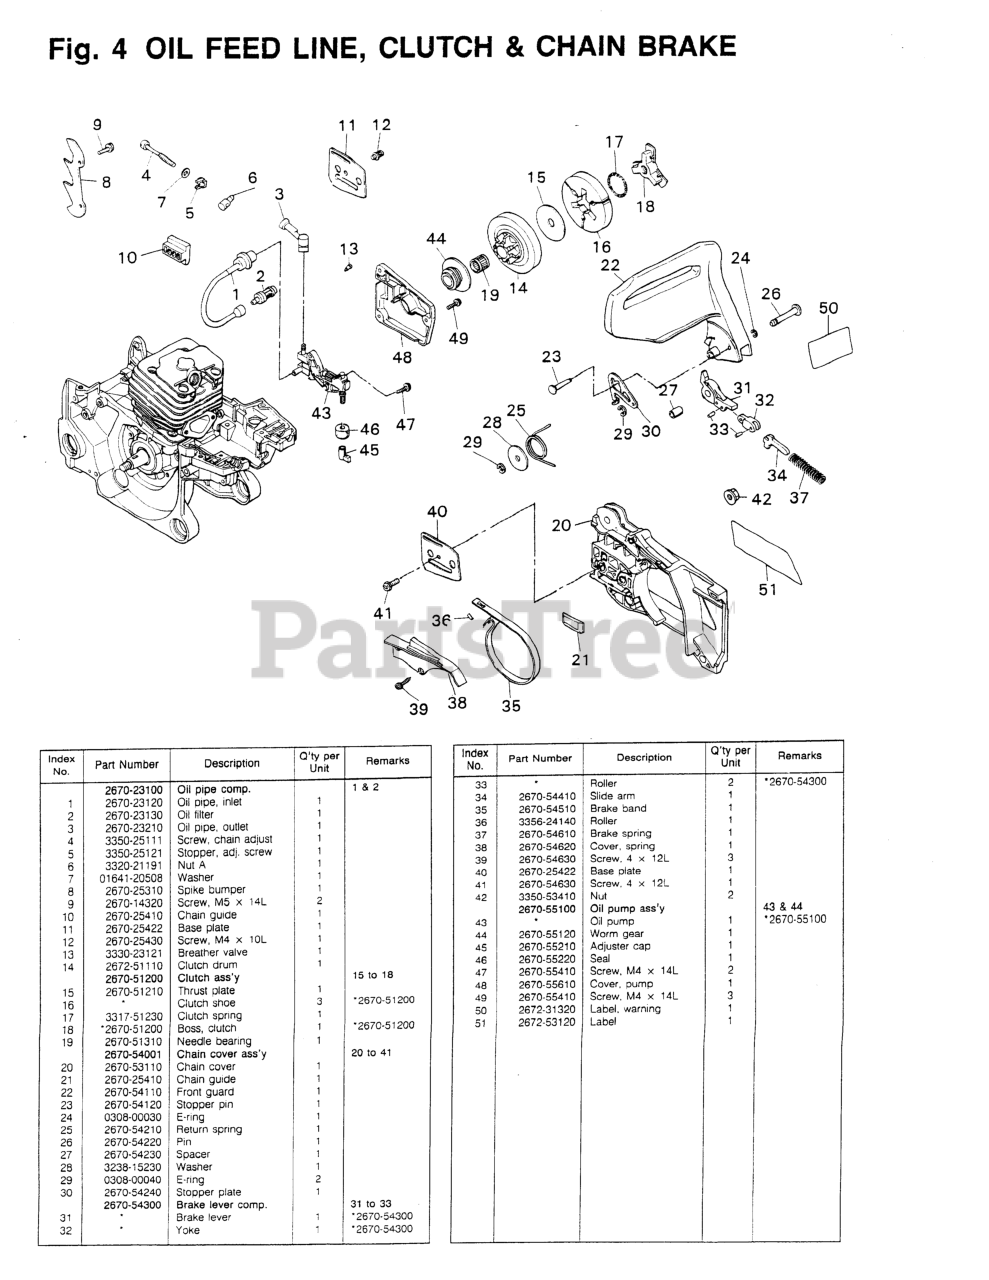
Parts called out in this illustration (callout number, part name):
1	PIPE, OIL
3	PIPE, OIL OUTLET
4	ADJUST SCREW
5	STOPPER, ADJUS
6	NUT (A)
7	WASHER, M5 X .8
8	SPIKE
9	SCREW (REPLACES 2616-24320)
10	GUIDE, CHAIN
11	PLATE (USE 2810-25421)
13	VALVE (RPLS -23120)
15	PLATE, THRUST
20	COVER, CHAIN (USE -53111)
21	GUIDE, CHAIN
24	RING, SNAP, M3
25	SPRING, RETURN
26	PIN
28	WASHER
29	RING, SNAP, M4
34	ARM, SLIDE
35	BAND, BRAKE
36	PIN
37	SPRING, BRAKE (RPLS. 50030121)
38	COVER (USE -54621)
39	SCREW
40	PLATE (USE 2810-25421)
41	SCREW
42	NUT
44	GEAR
45	ADJUSTER CAP
46	SEAL
47	SCREW
48	COVER, PUMP
49	SCREW
50	LABEL, KICKBACK
51	LABEL, CHAIN COVER
NI	COVER, CHAIN A
